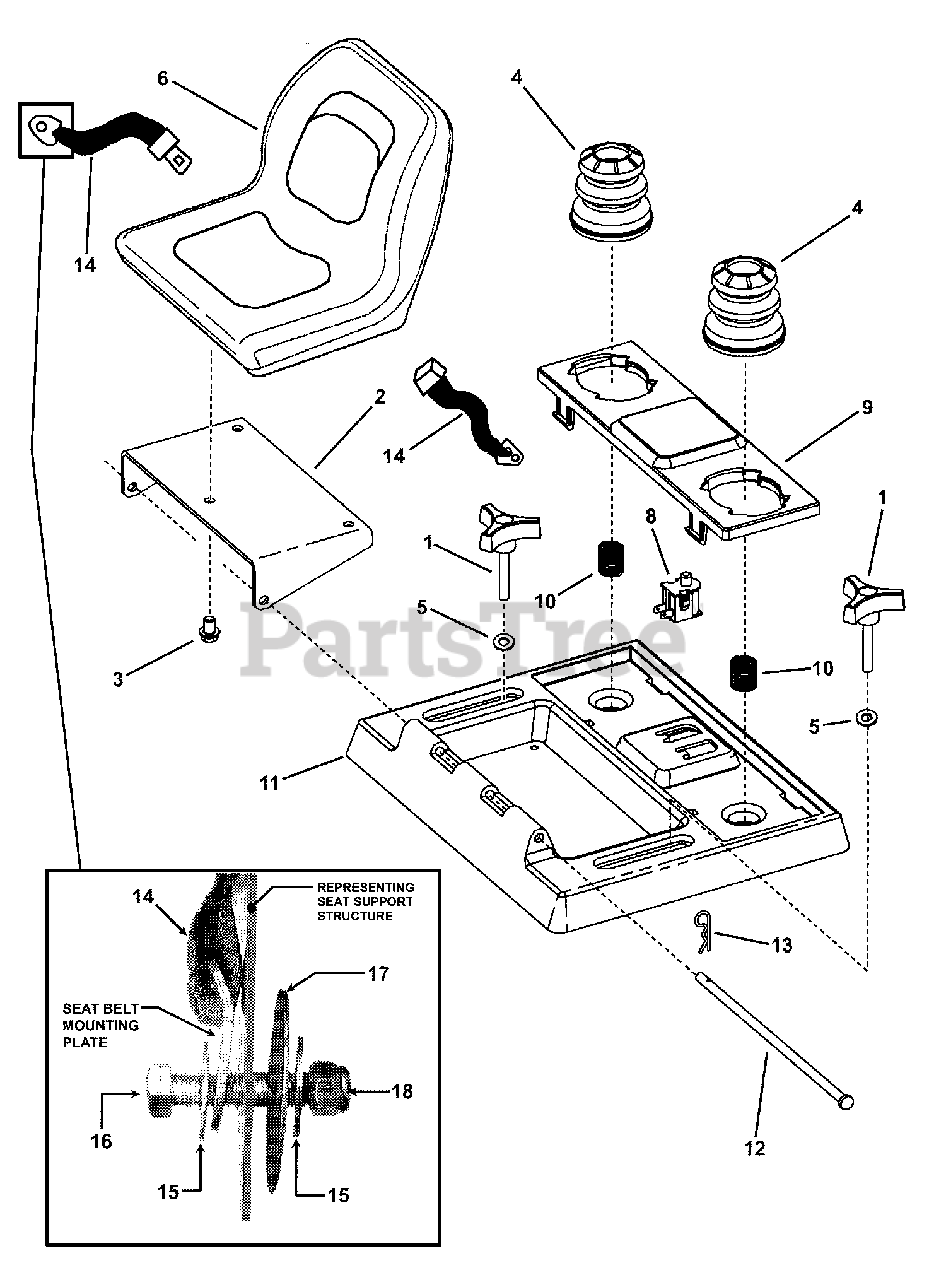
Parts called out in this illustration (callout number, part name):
13	HAIR PIN, 3/32 x 1-1/2"
14	SPRING, SEAT SUPPORT
14	SEAT BELT, 60" (incl. Ref. Nos. 16 thru 18)
15	MOUNT, SEAT STOP - RED
15	WASHER, 7/16" Flat (Type A, Wide)
16	PLATE, FOOT REST - RED
17	WELD, PLATE, SEAT MOUNT - RED
17	* WASHER, 1/2" I.D. x 2-1/2" O.D. Flat
18	VINYL CLAMP
18	* NUT, 7/16-20 Hex Nyloc
19	SAFETY WALK, FLOOR REST, 16.00 X 6.00
20	SAFETY WALK, FLOOR PLATE, S50X, 10X17.13
21	SAFETY WALK, 4.00 X 7.50
22	BOLT, 3/8-16 X 1" GD5 CZ
23	WASHER, 3/8 SAE
24	ARM REST (SET OF TWO) (SV)
25	SPRING, Extension, Seat Adjustment (BLK or SLVR) (3-1/2" Total unstretched length.)
26	KIT, SEAT RAILS (COMPLETE)(SV)
